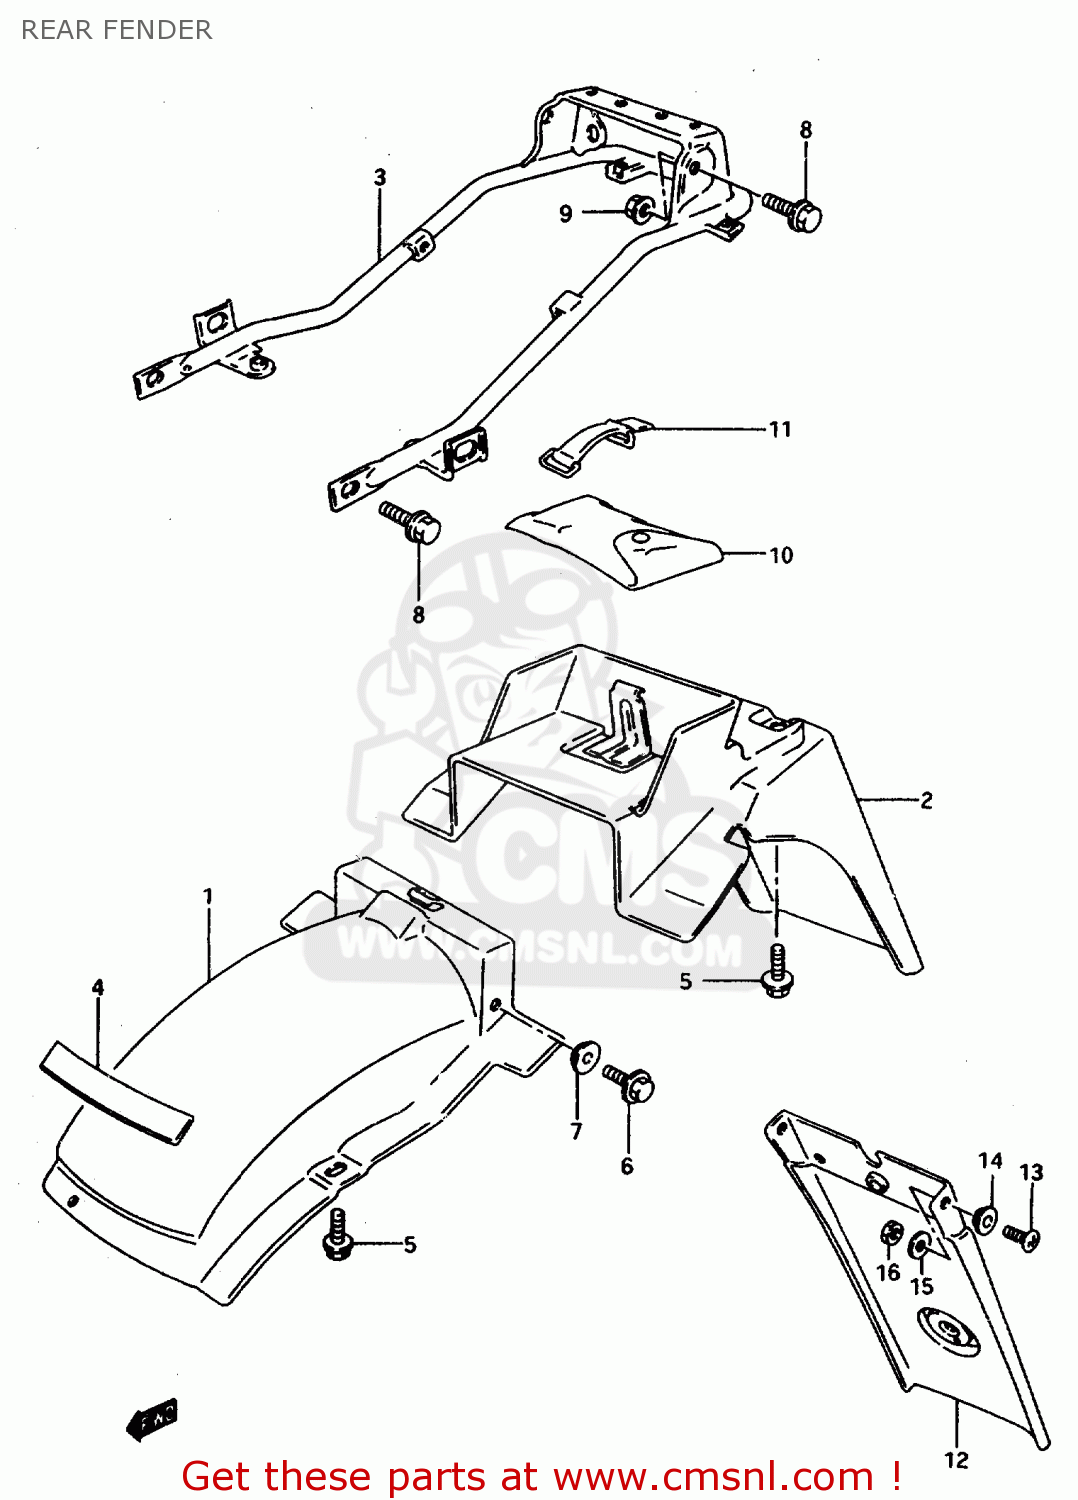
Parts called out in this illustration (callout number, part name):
1	BODY, REAR FENDER FRONT
2	BODY,RR FENDER RR
3	REINFORCEMENT, REAR FENDER
4	CUSHION, REAR FENDER
5	BOLT
6	BOLT(6X16)
7	WASHER
8	BOLT
9	NUT
10	TOOL ASSY
11	BAND
12	MUDGUARD,RR FENDER
13	SCREW
14	WASHER
15	WASHER
16	NUT 6MM
